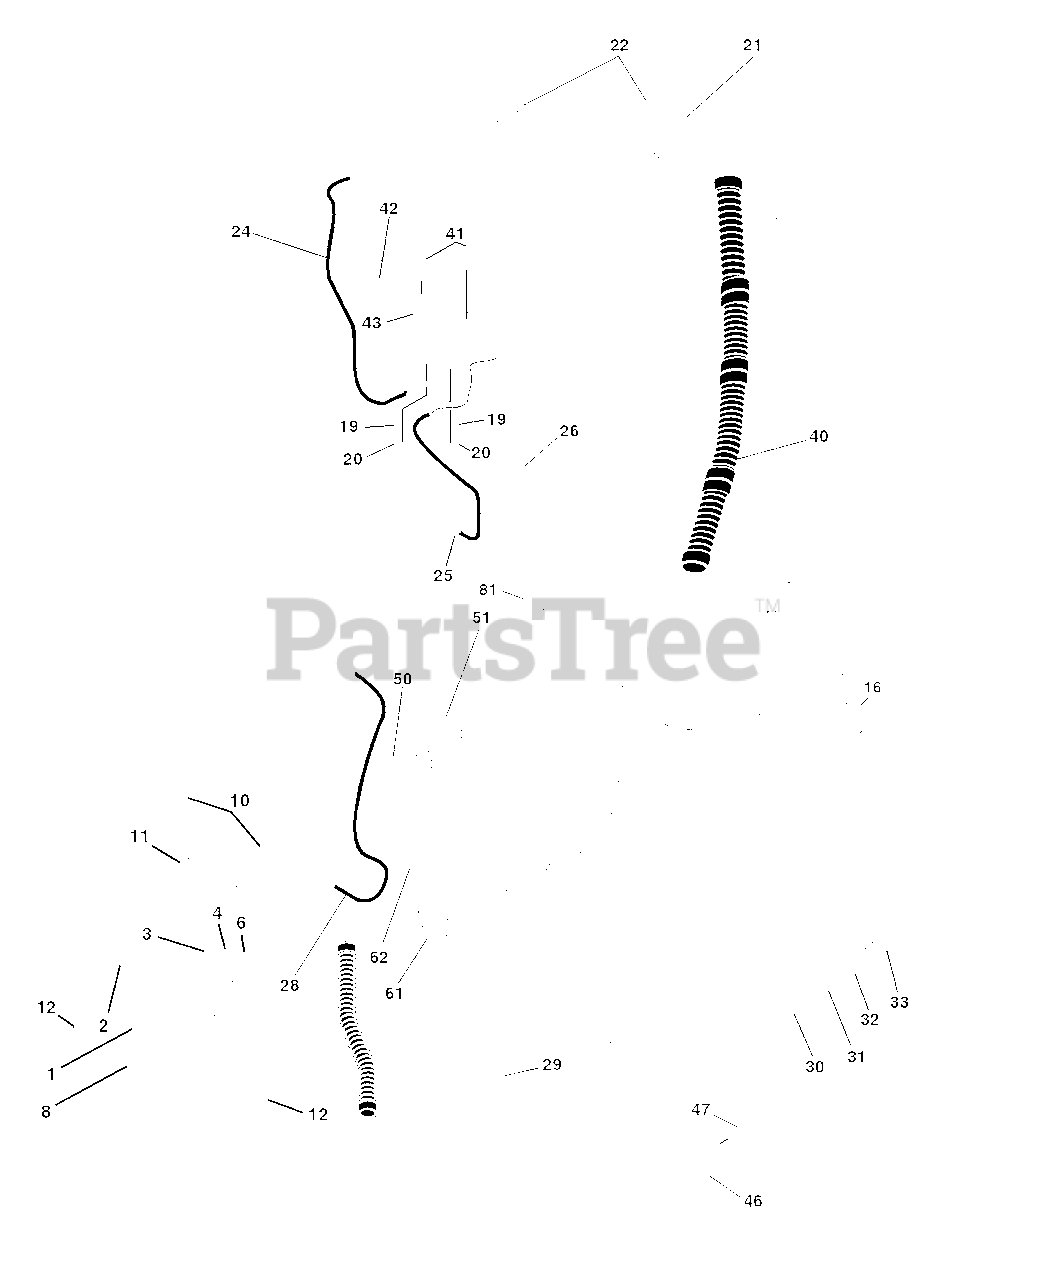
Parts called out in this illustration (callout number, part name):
1	Battery
2	Bolt Hex Head 1/4-20 x 3/4
3	Washer, Lock 1/4
4	Washer 9/32 x 5/8 x 16 Ga
6	Nut Fin Hex 1/4-20
8	Tray, Battery
10	Bolt, Btr Frt 1/4-20 x 7-1/2 Zinc
11	Holddown Battery Front Mount
12	Nut Push Nylon 1/4" Battery Frt.
16	Switch Interlock Push-In
19	Washer, Lock 1/4
20	Nut, Jam Hex 1/4-20
21	Harness Socket Light w/4152J
22	Bulb Light
24	Cable, Starter
25	Cable, Battery
28	Cable, Ground
29	Switch, Plunger
30	Switch, Ign
31	Nut, Ignition Switch
32	Cover Switch Key
40	Harness Ign.
41	Screw 1/4-20 x 1/2
42	Cover, Terminal Red
43	Solenoid
46	Meter Hour
47	Screw #10-24 x 1/2
50	Switch, PTO
51	Ring Retainer PTO
61	Light Pkg Asm
62	Bulb, Light Pkg.
81	Relay Asm.
